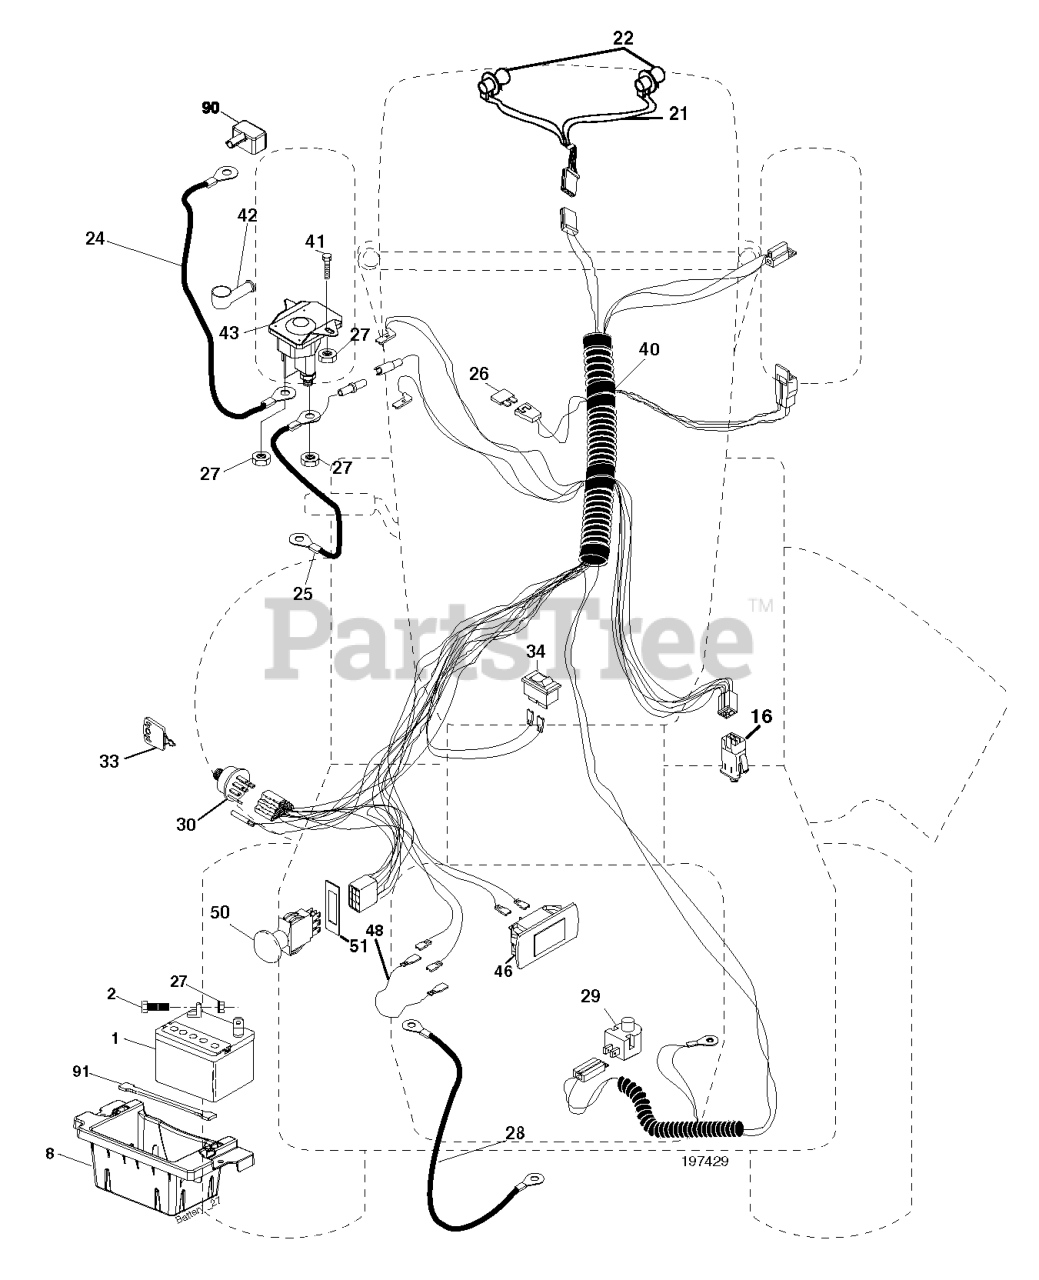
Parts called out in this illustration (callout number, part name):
1	BATTERY 12V .35 AMP
2	BOLT.HEX.1/4.X.3/4.DICHROMATE
8	BOX.BATTERY.MOUNT.FRONT.LT
16	SWITCH INTERLOOK PUSH-IN
21	HARNESS.W/LIGHT SOCKET
24	BATTERY CABLE GT
25	CABLE BATTERY 6 GA 22" W/16W
26	FUSE 20AMP
27	NUT
28	CABLE GROUND 6 GA 21" 90T BLK
29	SWITCH.SEAT.DP W/RAMPS
30	SWITCH.IGN.DELTA.W.LGH.ROS
33	KEY MLD GEN DELTA
40	HARNESS.IGN.ELEC.STL.N/RELY.05
41	BOLT
42	TERMINAL COVER
43	SOLENOID.W/BRASS.PLUNGER
46	GAUGE.SERVICEMINDER.HR
48	ADAPTER.AMMETER
50	RP.PTO.SWITCH.8 TERMINAL.BLACK
51	FRAME RETAINING RING
90	COVER TERMINAL
91	STRAP.BATTERY.MOUNT.FRONT(2 2)
